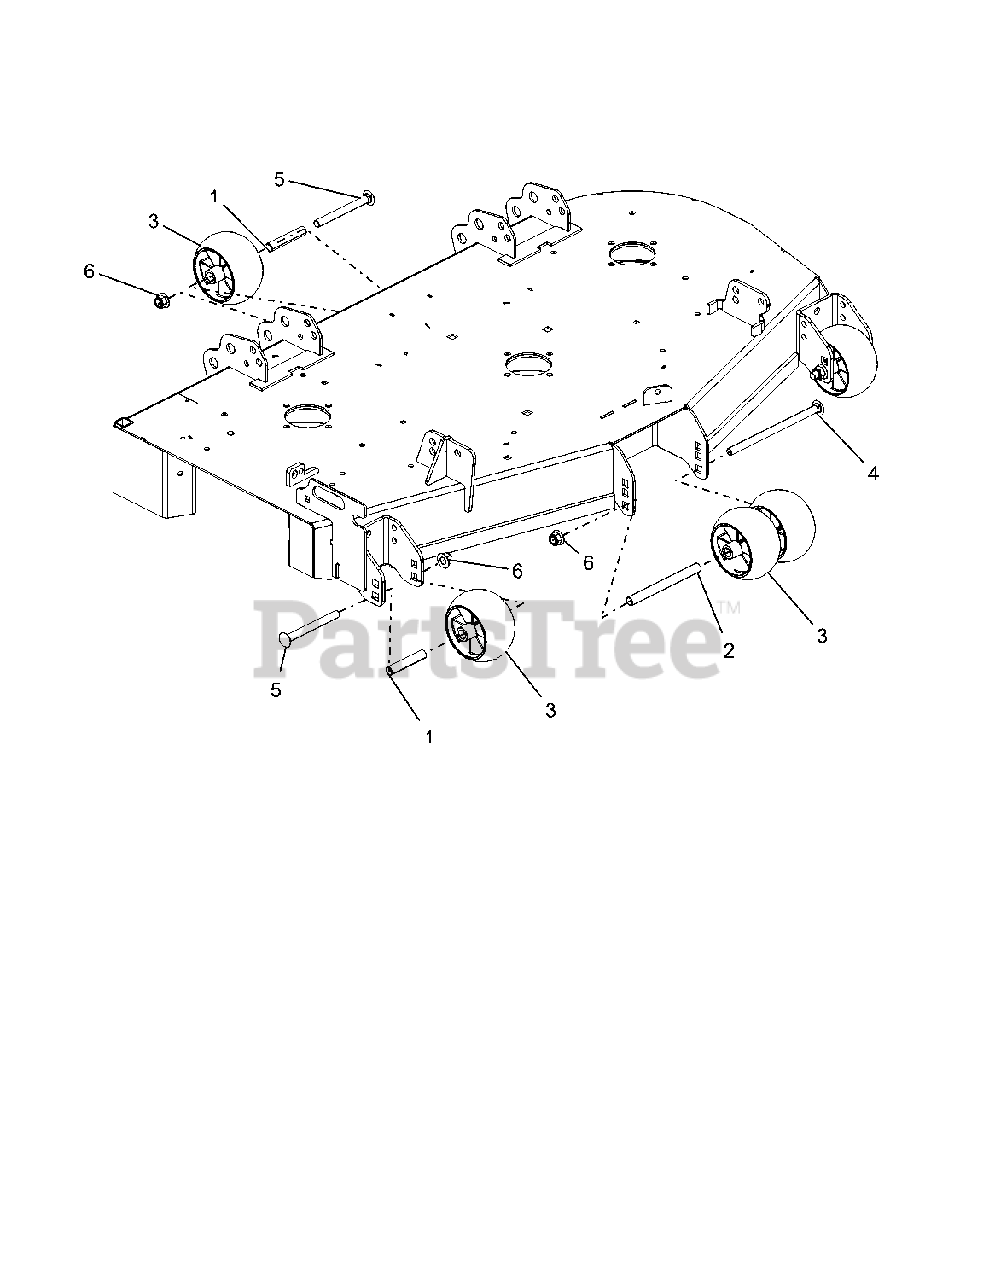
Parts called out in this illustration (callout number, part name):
1	SPACER, .510X.625X3.35
2	SPACER, .510 X .625 X 6.50
3	ANTI-SCALP WHEEL - 5X3 CTR
4	BLT-RDHDSQNK .50-13X8.50 Y
5	BLT-RDHDSQNK .50-13X5.00 G5 YWZC
6	NUT-LK-NYL-FLG .50-13 YWZC
